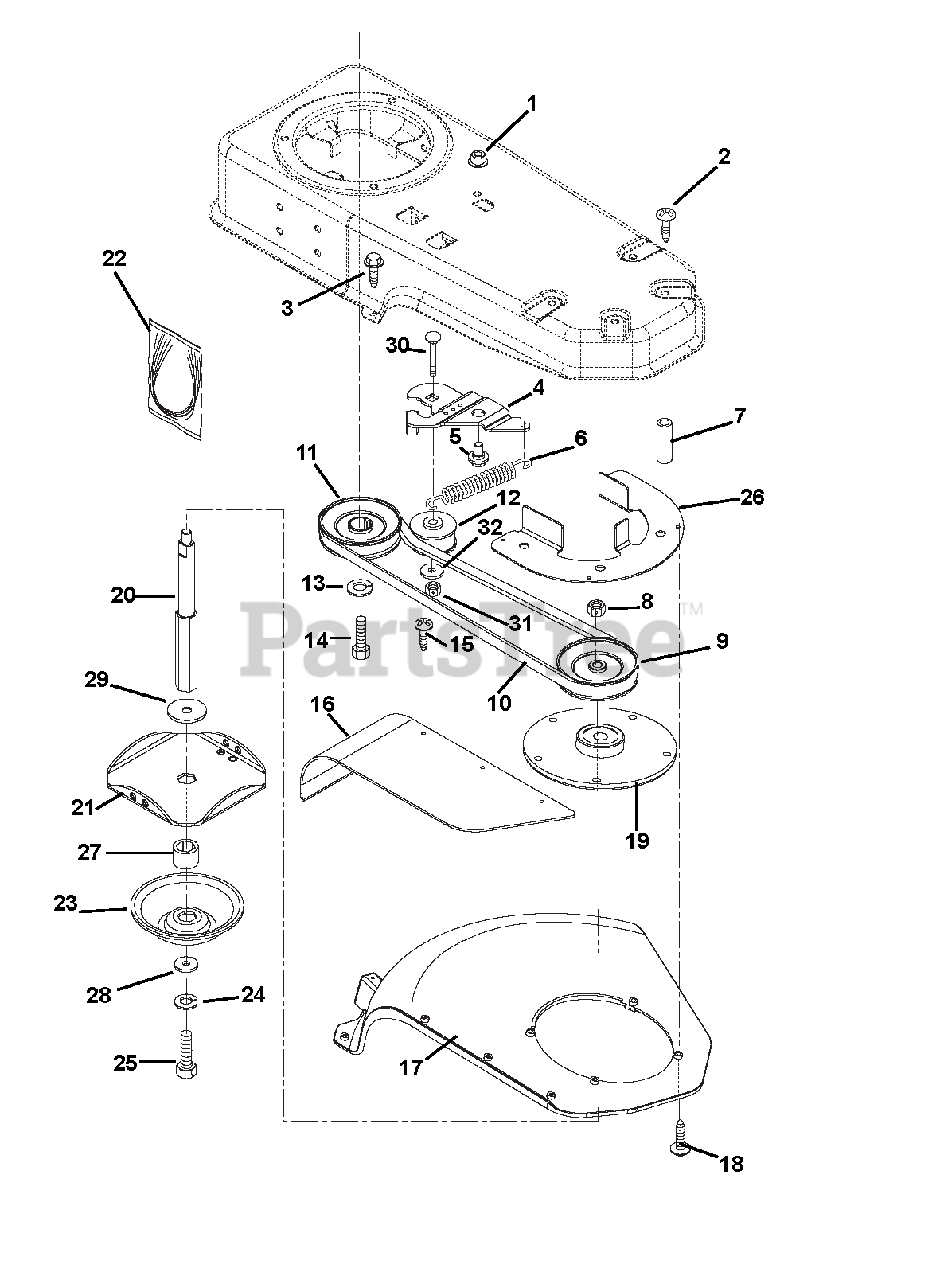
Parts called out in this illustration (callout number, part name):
1	NUT-LK-CTR-FLG .38-16 YWZC
2	@SCR-TAP.375-16X2.75 HWH TR YZ
3	SCR-TAP 10-24X.75 HWH TR YWZC
4	BRACKET - IDLER
5	BOLT-SHLDR .375-16X.150
6	SG-TENS .035X.45X2.75 WLD 3.5
7	BSHG-SPCR .406X.625X1.90
8	NUT-LK-FLG .375-24 GR5 YWZC
9	PLY-V 3.50 OD X .87 WIDE (CUT)
10	V-BELT, HA-RAW EDGE
11	SHEAVE-ENGINE 3.50 ODX.87 WIDE
12	IDLER - FLAT 1.875OD X .75WIDE
13	@WSHR-LK .38X.094 REG YWZC
14	BLT-HEX .38-24X1.0 YWZC GR5
15	SCR-TAP #10-16 X .625 HWH
16	GUARD - DEBRIS
17	SHIELD - TRIMMER
18	SCR-TAP 10-24X.75 HWH TR YWZC
19	HOUSING - JACKSHAFT
20	SHAFT - CUTTER - HEX
21	CUTTER - DISK
22	LINE - CUTTER 18" LG PKG OF 6
23	GUIDE - HEIGHT - HEX
23	GUIDE - HEIGHT - LONG LIFE
24	@WSHR-LK .31X.078 REG YWZC
25	@BLT-HEX .31-18X.75 GR5 YWZC
26	FINGER - BELT
27	SPACER - HEX
28	WSHR-FL-STL .344X1.125X.135
29	SHIELD - DUST
30	@BLT-RHDSSQNK .38-16X1.50 G5YZ
31	@NUT-LK-CTR .38-16 YWZC
32	@WSHR-FL-STL.406X.812X.065 YWZ
